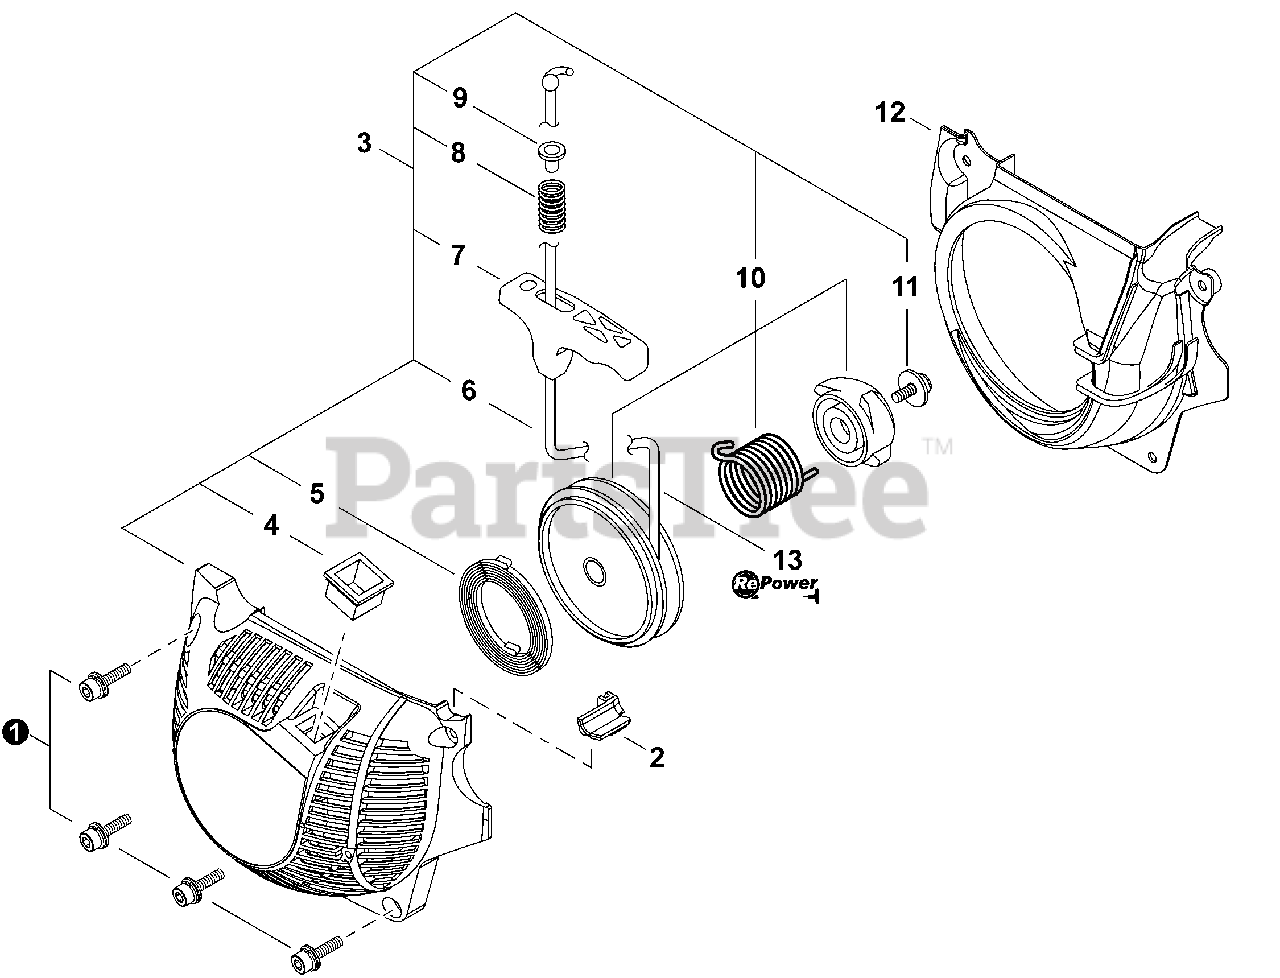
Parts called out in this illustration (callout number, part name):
1	BOLT M4×16
2	GROMMET, NEEDLE
3	STARTER ASSY, RECOIL
4	GUIDE, ROPE
5	SPRING, RECOIL
6	ROPE, STARTER Ø3.8×750
7	GRIP, STARTER
8	SPRING, COMPRESSION
9	RETAINER, ROPE
10	REEL KIT, ROPE
11	SCREW 5
12	COVER, FAN
13	ROPE, STARTER - REPOWER BULK
